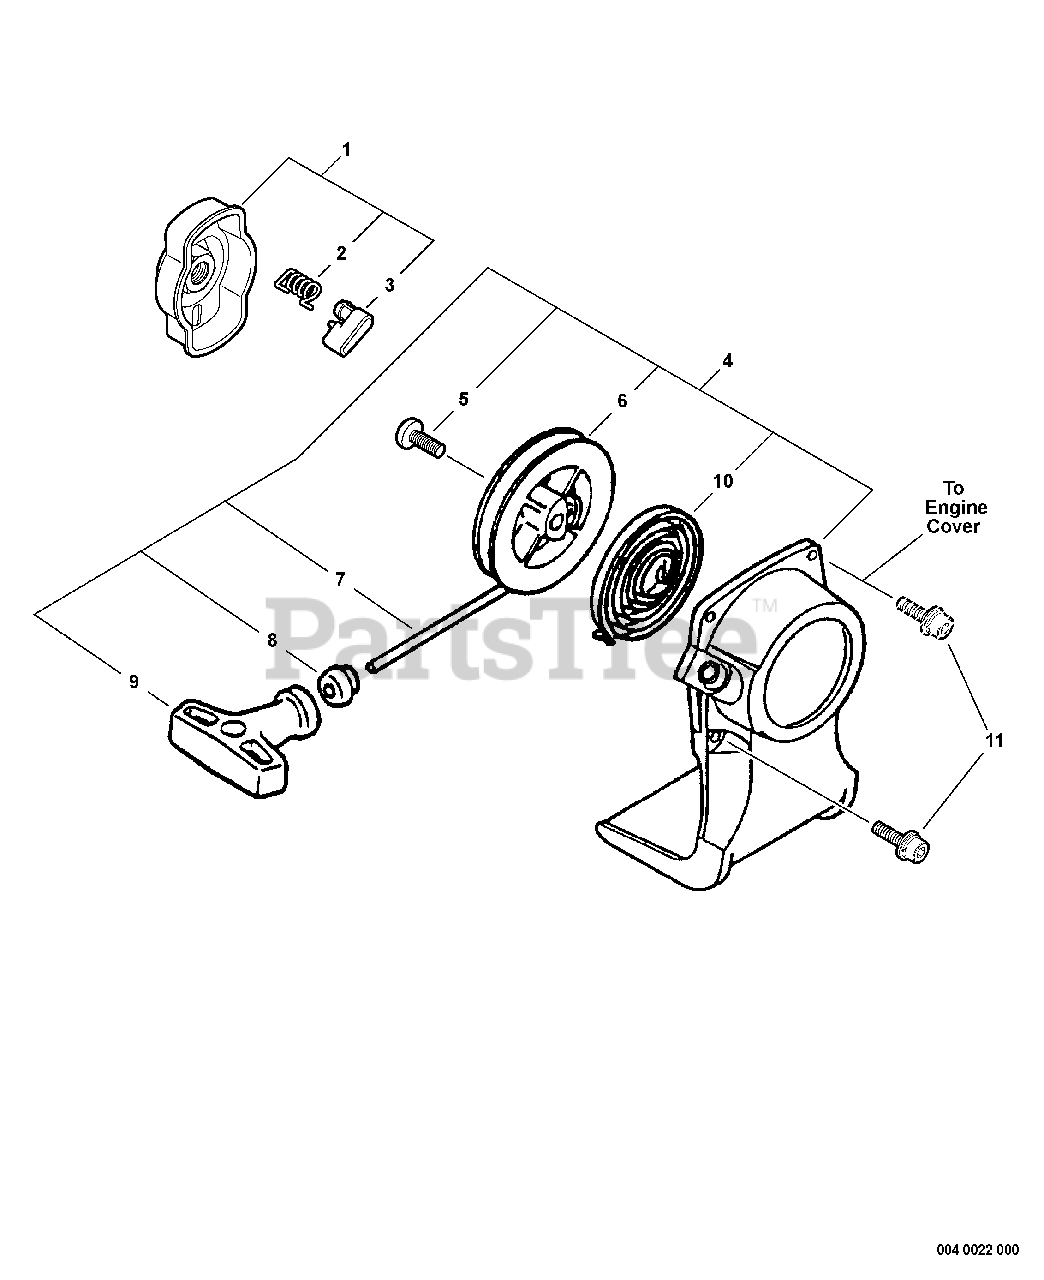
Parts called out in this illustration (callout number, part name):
1	PAWL ASSY, STARTER
2	SPRING, RETURN
3	PAWL, STARTER - BLACK
4	STARTER ASSY
5	SCREW
6	REEL, ROPE
7	ROPE, STARTER 3.0×1000
8	GUIDE, ROPE
9	GRIP, STARTER
10	SPRING, RECOIL
11	BOLT 4×16
